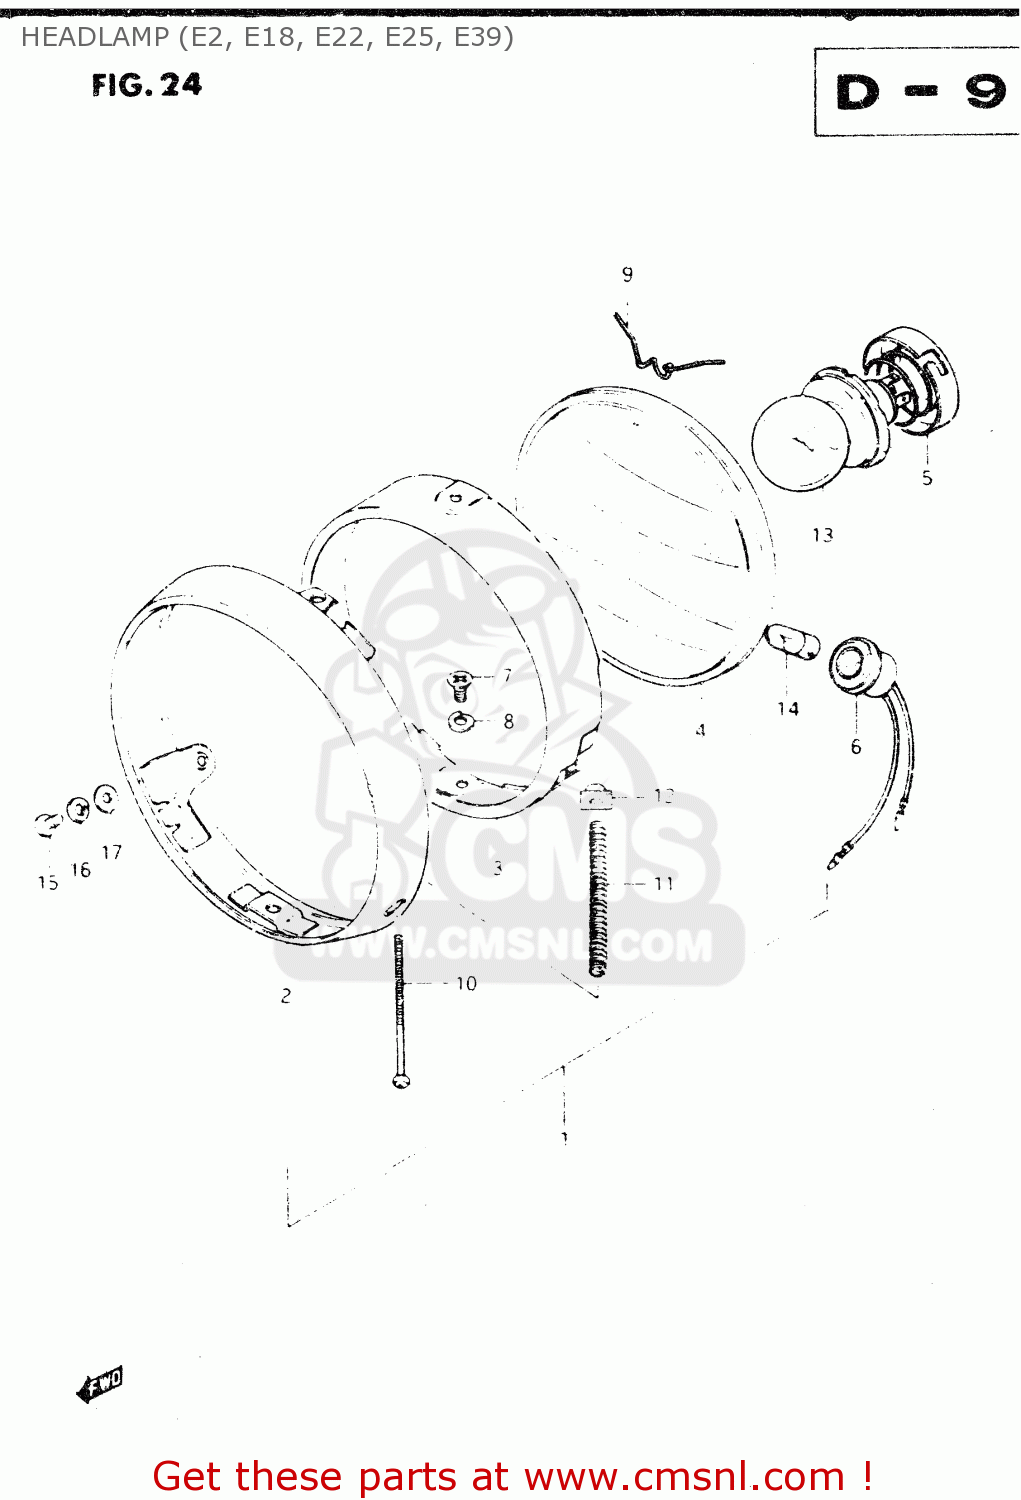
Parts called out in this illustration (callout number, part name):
1	HEADLAMP ASSY
2	RIM,HEADLAMP
3	RETAINER
4	LAMP UNIT
5	SETTER,BULB
6	SOCKET
7	SCREW
8	LOCK WASHER
9	SPRING
10	SCREW
11	SPRING
12	NUT
13	BULB(12V45/40W)
14	BULB(12V4W)
15	SCREW
16	LOCK WASHER
17	WASHER
